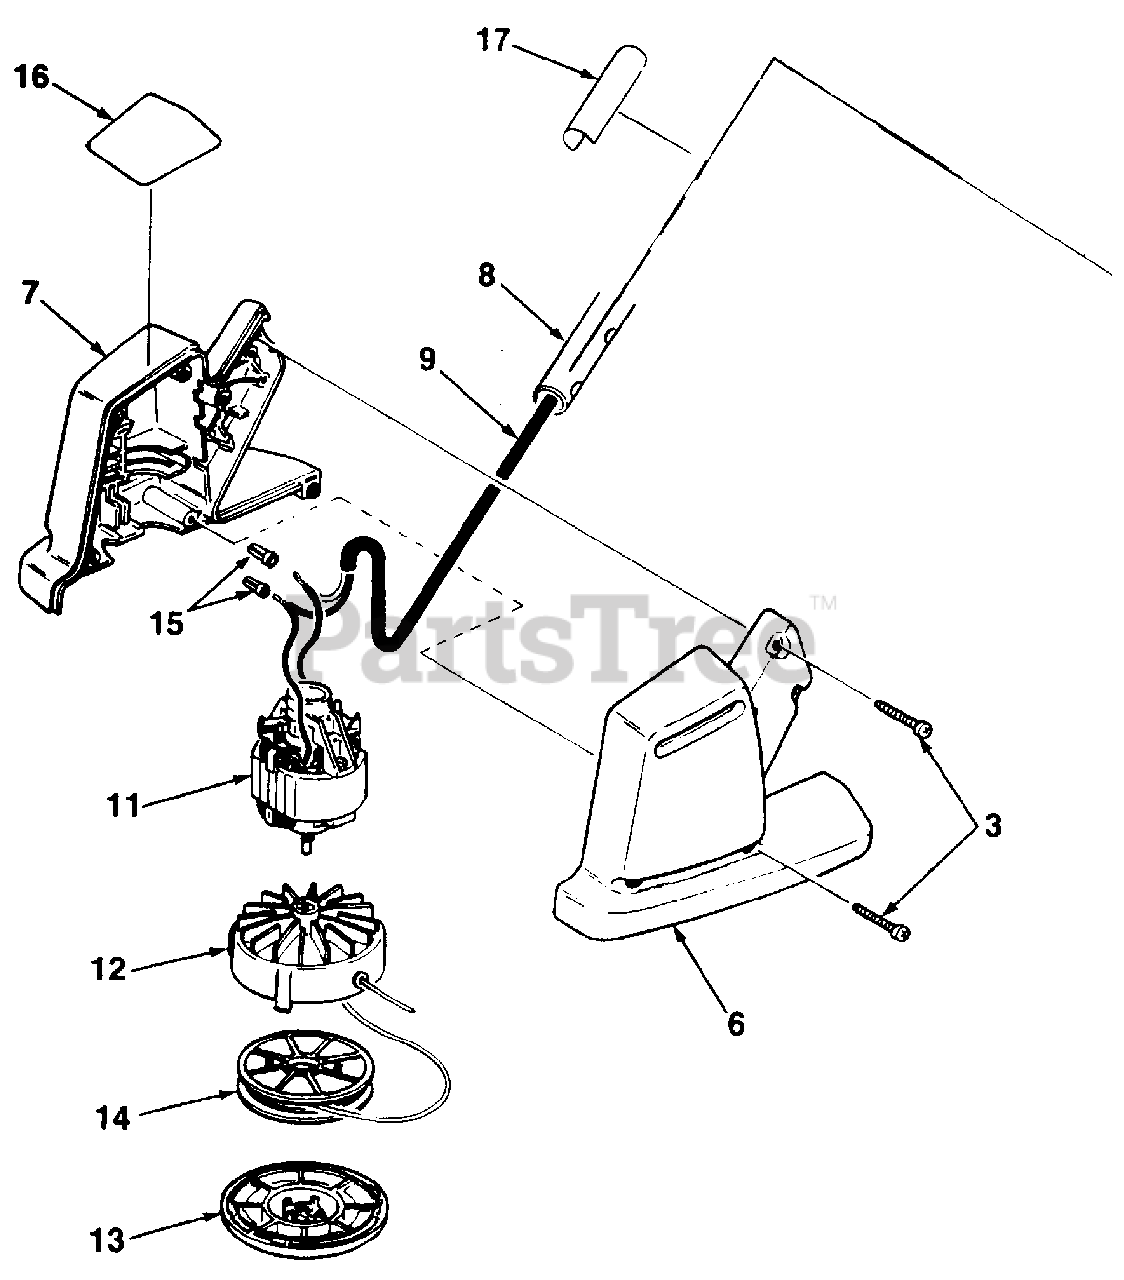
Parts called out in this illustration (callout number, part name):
3	SCREW- Thread forming 10-16 x 3/4
6	HOUSING- Motor (left)
7	HOUSING- Motor (right)
9	CABLE- Electrical
11	MOTOR- Electric 120V
12	HEAD- String
13	RETAINER- Spool
14	SPOOL & STRING
15	CONNECTOR- Wire
17	DECAL- Warning
